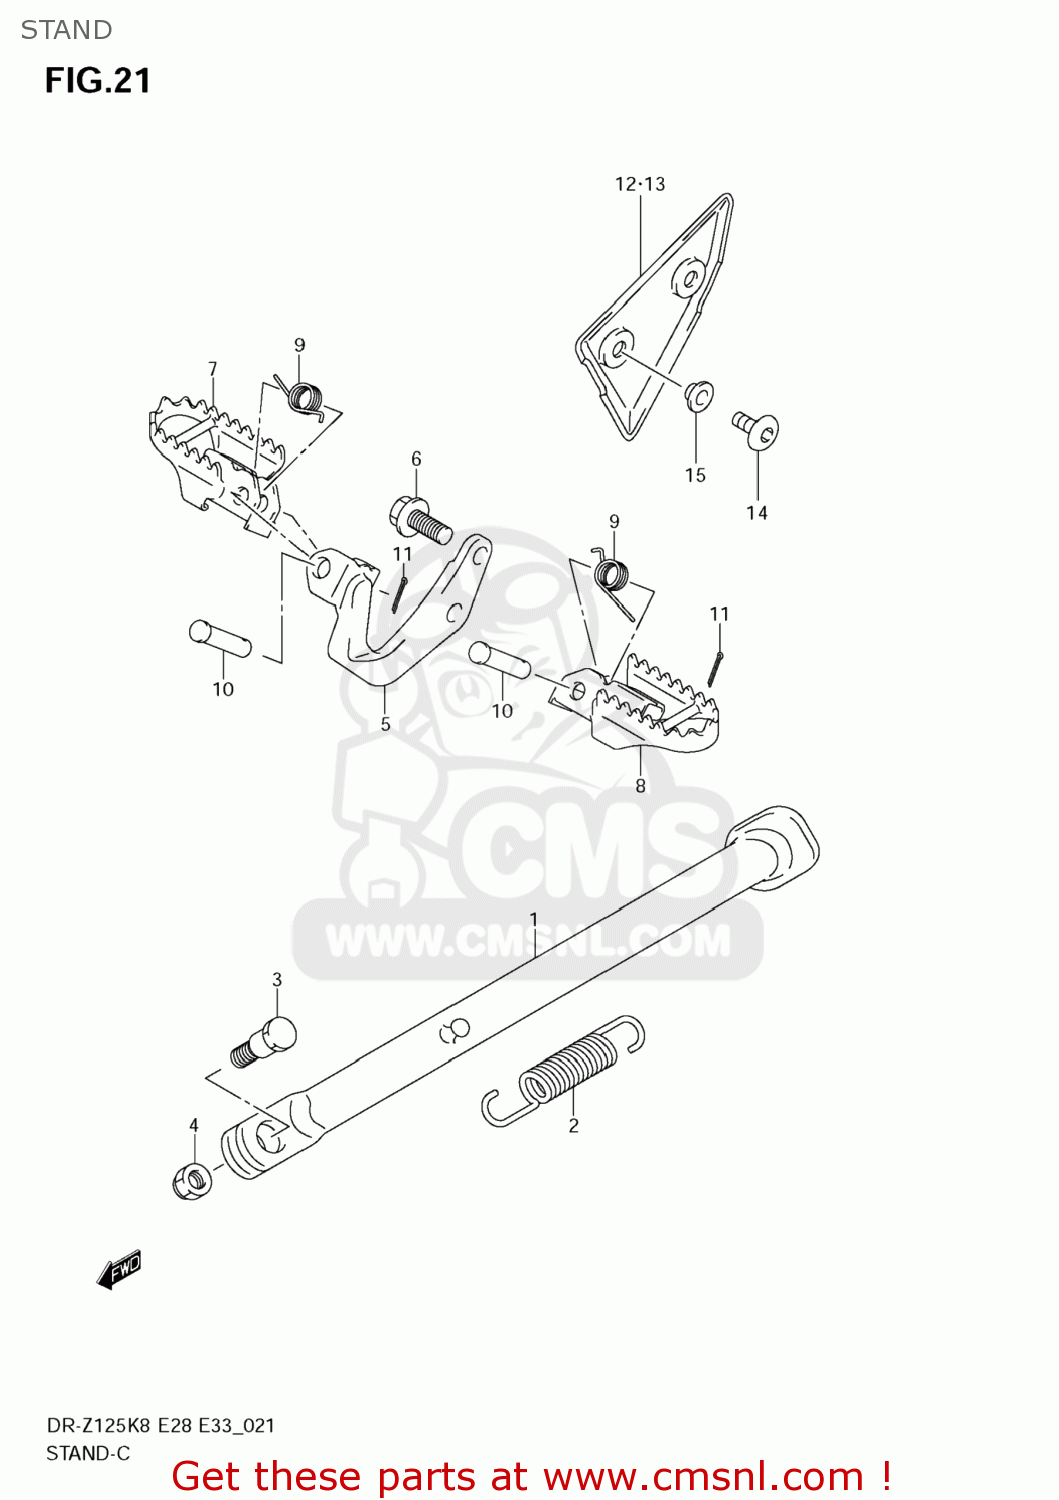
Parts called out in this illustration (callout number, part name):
1	STAND,PROP
2	SPRING
3	BOLT(10X33)
4	NUT,PROP STAND
5	BRACKET,FR FOOTREST,R
6	BOLT
7	FOOTREST,FRONT,RIGHT
8	FOOTREST,FRONT,LEFT
9	SPRING
10	PIN
11	PIN
12	GUARD,FR FOOTREST,R
13	GUARD,FR FOOTREST,L
14	SCREW(6X12)
15	WASHER
